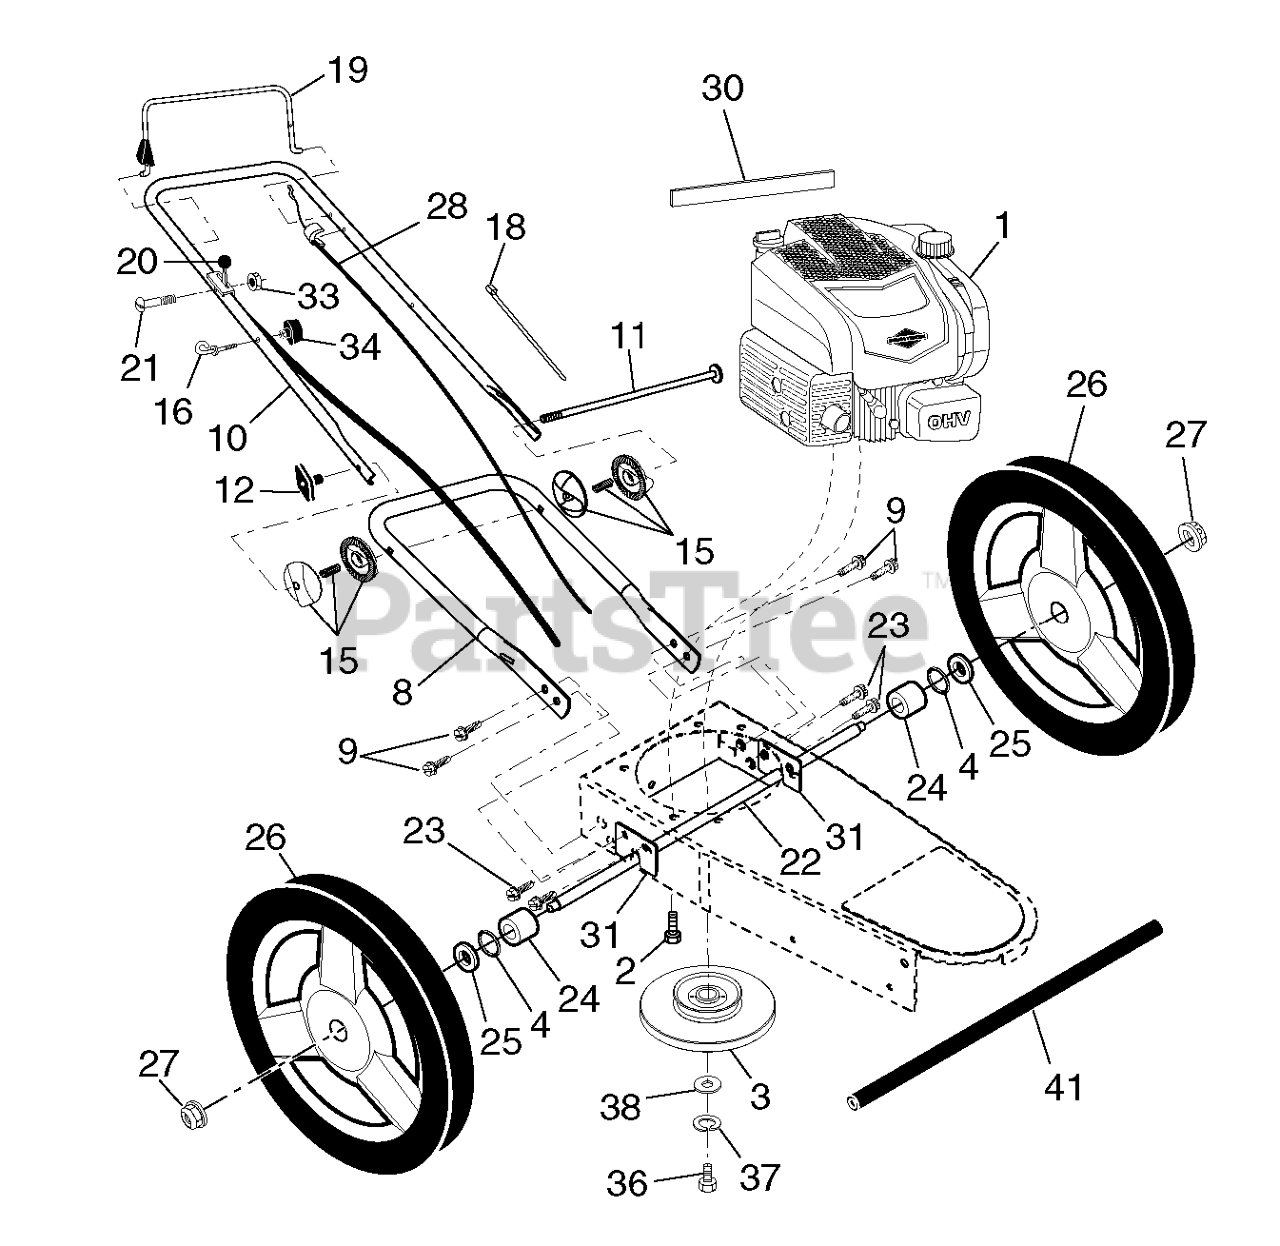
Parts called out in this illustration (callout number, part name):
2	BOLT 3/8-16X1-1/8
3	PULLEY, ENGINE
4	O-RING..070X.487.NEOPRENE
8	HANDLE.LOWER.STRING.TRIMMER.GR
9	BOLT.HEX.HD.WASHER.5/16-18X.75
10	HANDLE.UP.STRING.TRIMMER.GREY
11	BOLT.HANDLE.WHEELED.TRIMMER
12	KNOB, DEFLECTOR
15	ADJSTR.ASSEM.HANDLE.WHLD.TRIMM
16	GUIDE.ROPE.BLK.ZINC.CHROM
18	TIE GUIDE
19	BAIL.ARM.ASM.TRIMMER.668
20	CONTROL.ENGINE.STOP.BRAKE
22	AXLE.TRIMMER
23	BOLT.HEX.HD.WASHER.5/16-18X.75
24	SPACER.AXLE.STRING.TRIMMER
25	WASHER.FLAT.1/2
26	WHEEL.12X1.75.CF H3SPK.RAD3.BB
27	NUT.HEX.FLANGE.3/8-16.LOCKNUT
28	CABLE.DRIVE.TRIMMER
30	DECAL.TRIMMER.CHASSIS.SYM
31	BRACKET, AXLE
33	NUT.HEX.FLANGE.1/4
34	T-KNOB.NEW ROPE GUIDE
36	SCREW, HEX HD 3/8-24 X 1-3/8
37	LOCKWASHER
38	WASHER,HARDEN
41	TUBE.AXLE.TRIMMER.BLACK
